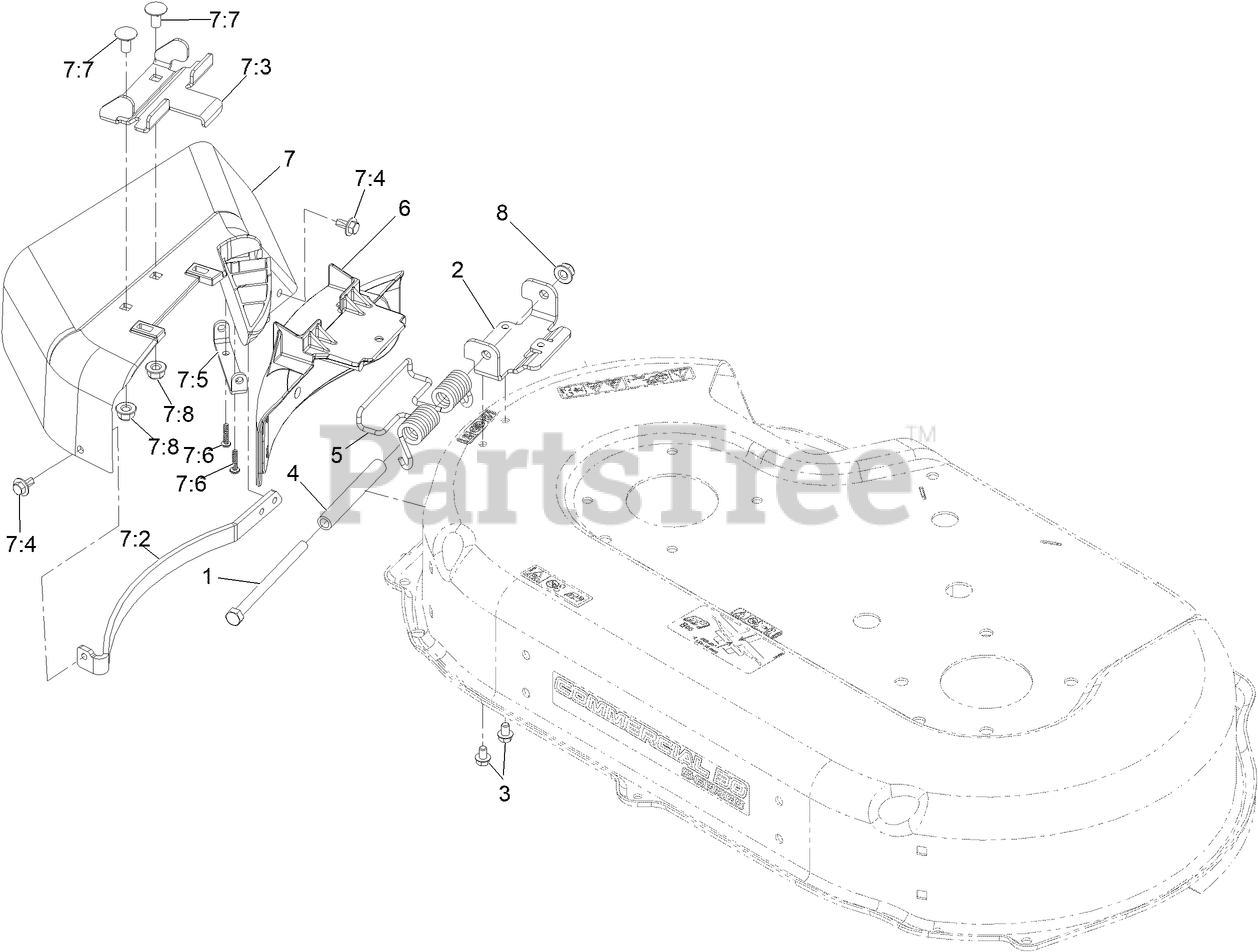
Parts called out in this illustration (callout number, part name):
1	SCREW-HH
4	SPACER
5	SPRING-TORSION
6	COVER-DISCHARGE
7	SIDE DISCHARGE CHUTE ASM
7:2	GUARD-CHUTE
7:3	BRACKET-CHUTE
7:4	SCREW-HHFTF
7:5	BRACKET-COVER
7:6	SCREW-PPH
7:7	SCREW-CARR
7:8	NUT-HF, NI
8	NUT-HF, NI
